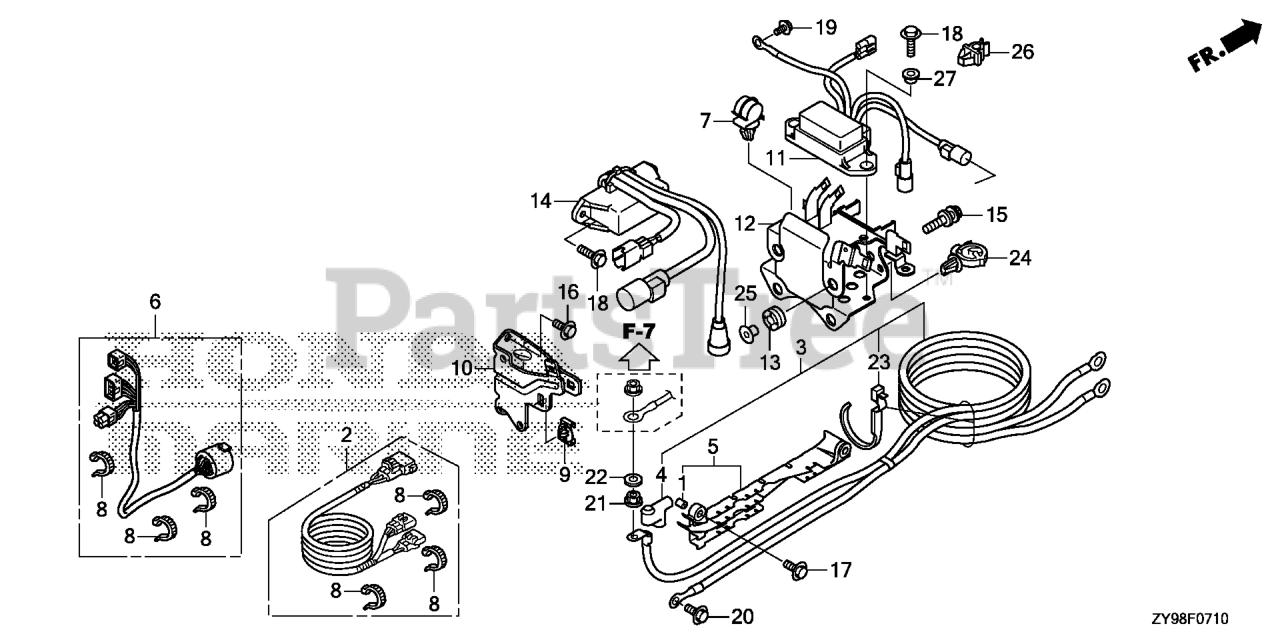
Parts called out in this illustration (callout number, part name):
1	COLLAR, DISTANCE (6.5X11X7.5)
3	CABLE ASSY., STARTER
4	COVER, STARTER TERMINAL
5	HOLDER, STARTER CABLE
5	HOLDER COMP
7	CLAMP, WIRE
9	CLIP, CONNECTOR HOLDER (B)
10	BRACKET, FUSE BOX
11	RELAY ASSY., POWER TILT
12	BRACKET, RELAY
13	GROMMET, RELAY BRACKET
14	RELAY ASSY., MAIN
15	BOLT-WASHER (6X27) (CT200)
15	BOLT-WASHER (6X27)
16	BOLT, FLANGE (6X14) (CT200)
17	BOLT, FLANGE (6X20)
18	BOLT, FLANGE (6X14)
19	BOLT, FLANGE (6X12)
20	BOLT, FLANGE (8X18)
21	NUT-WASHER (8MM)
22	WASHER, PLAIN (8MM)
23	BAND, WIRE (165MM) (BLACK)
24	CLIP, WIRE HARNESS (25MM)
25	COLLAR, MODULE IGNITION CONTROL CASE (CDI)
25	COLR, CDI UNIT CASE
25	COLLAR (12X6.5)
26	CLIP, TUBE (3.5)
27	COLLAR, P.T.T. RELAY
27	COLLAR, PTT RELAY
